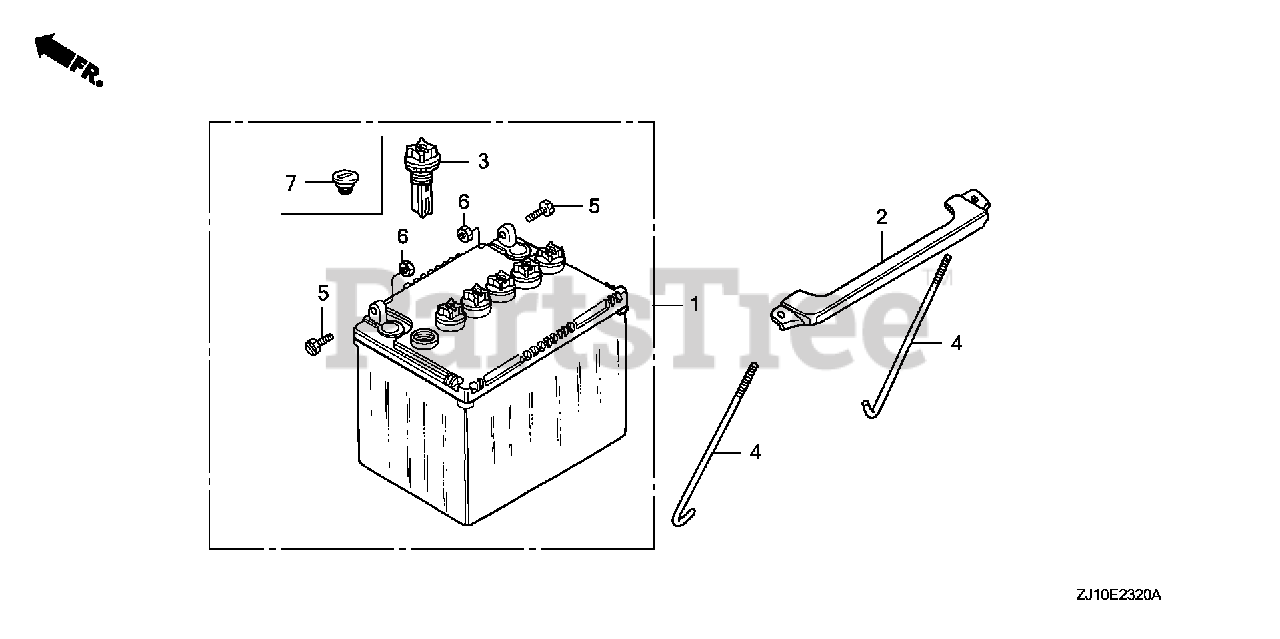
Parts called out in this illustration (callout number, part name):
1	BATTERY (34A19L-MF)9L-MF) (YUASA) (MSDS)
2	PLATE, BATTERY SETTING
3	PLUG, VENT (YUASA)
4	BOLT, BATTERY SETTING
5	BOLT, BATTERY TERMINAL
6	NUT, BATTERY TERMINAL
